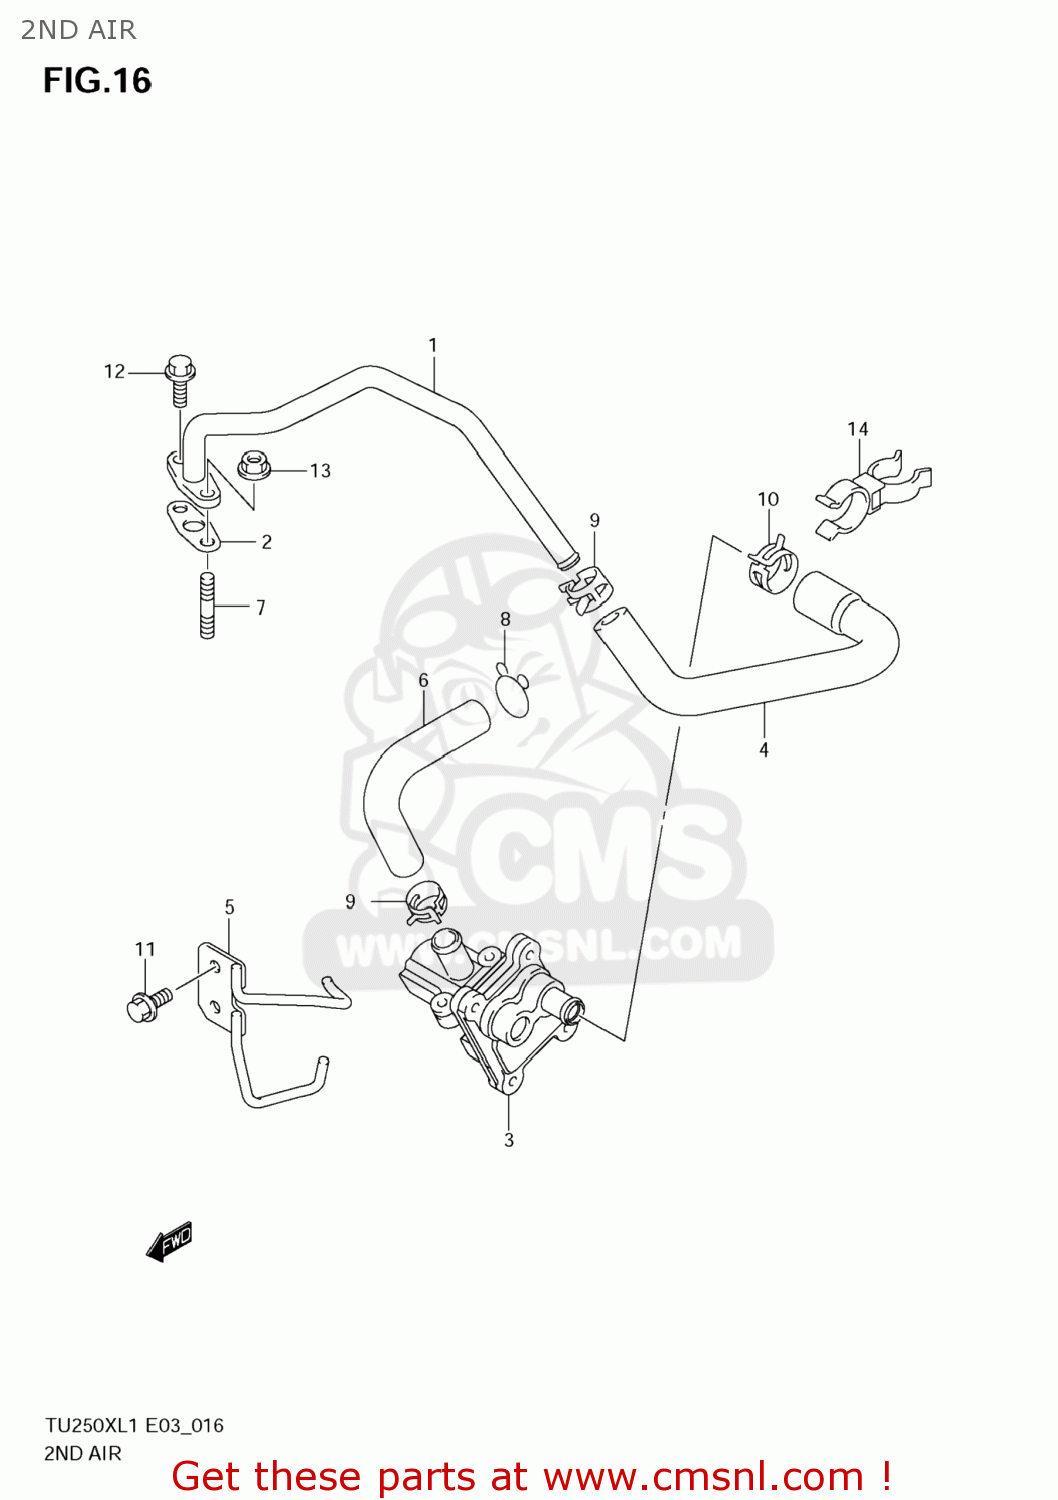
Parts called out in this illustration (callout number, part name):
1	PIPE,2ND AIR
2	GASKET,2ND AIR PIPE (NAS)
3	VALVE ASSY,2ND
4	HOSE,2ND AIR VALVE
5	BRACKET,2ND AIR VALVE
6	HOSE,2ND AIR CLEANER
7	BOLT,STUD
8	CLIP
9	CLIP
10	CLIP
11	BOLT
12	BOLT
13	NUT
14	CLAMP
